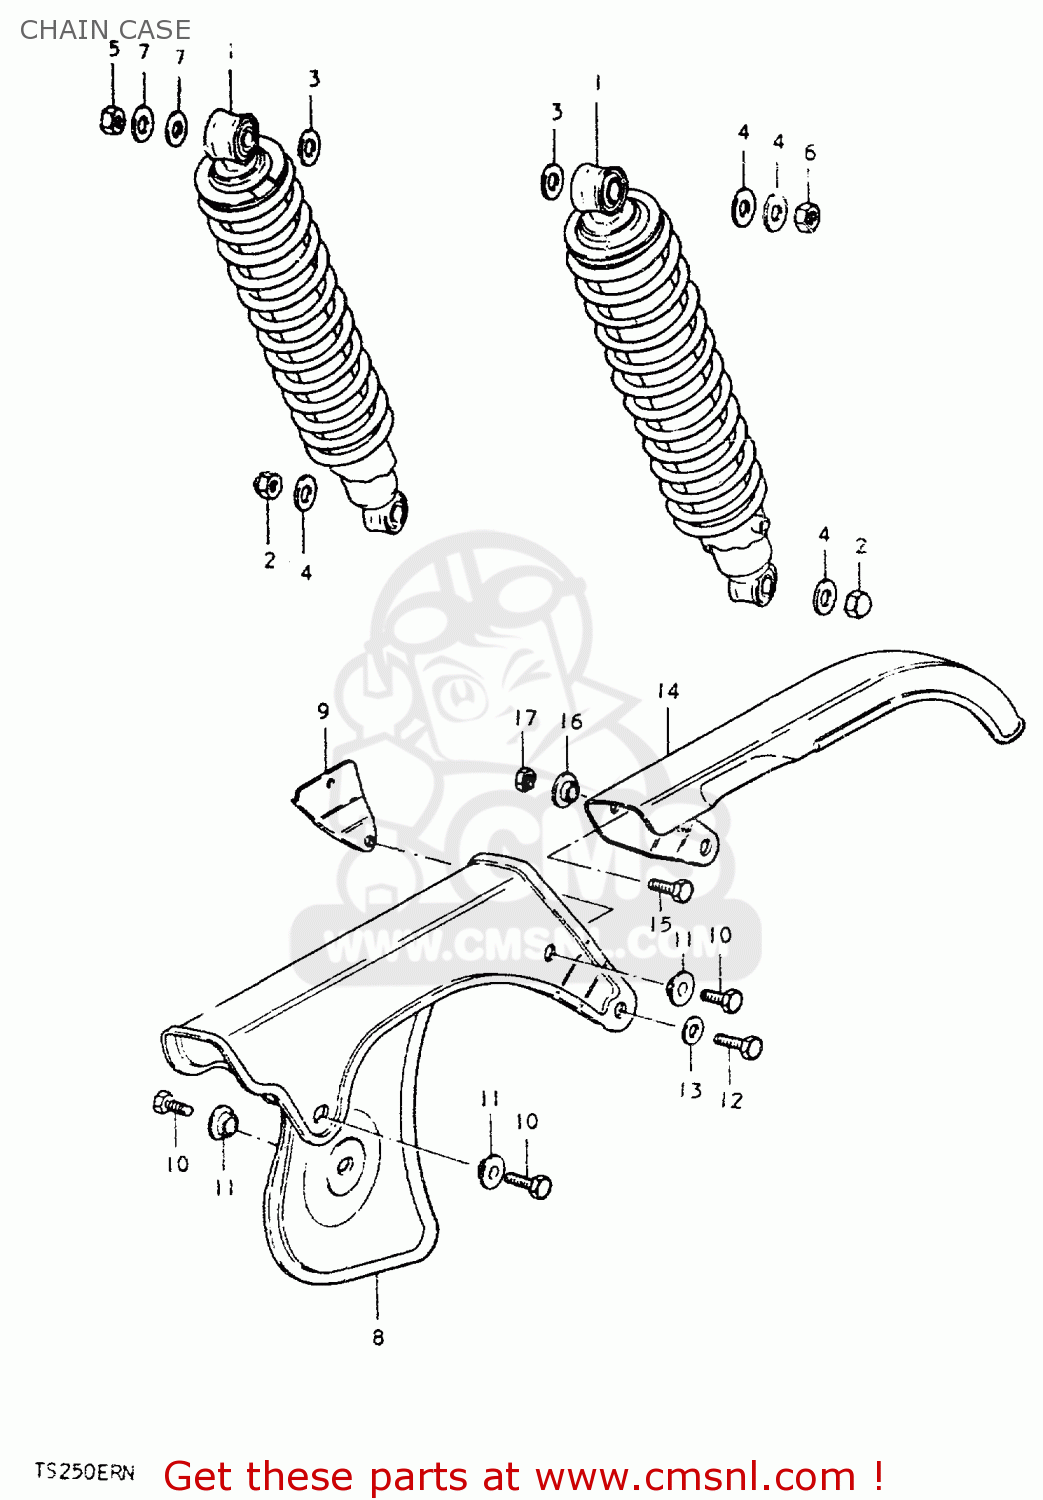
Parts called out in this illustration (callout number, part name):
1	ABSORBER ASSEMBLY,REAR SHOCK
2	NUT, LOWER LH
3	WASHER
4	WASHER
5	NUT
6	NUT
7	WASHER (12.5X24X3.2)
8	CASE,CHAIN
9	REINFORCEMENT,CHAIN CASE
10	BOLT(6X8)
11	WASHER
12	BOLT
13	WASHER
